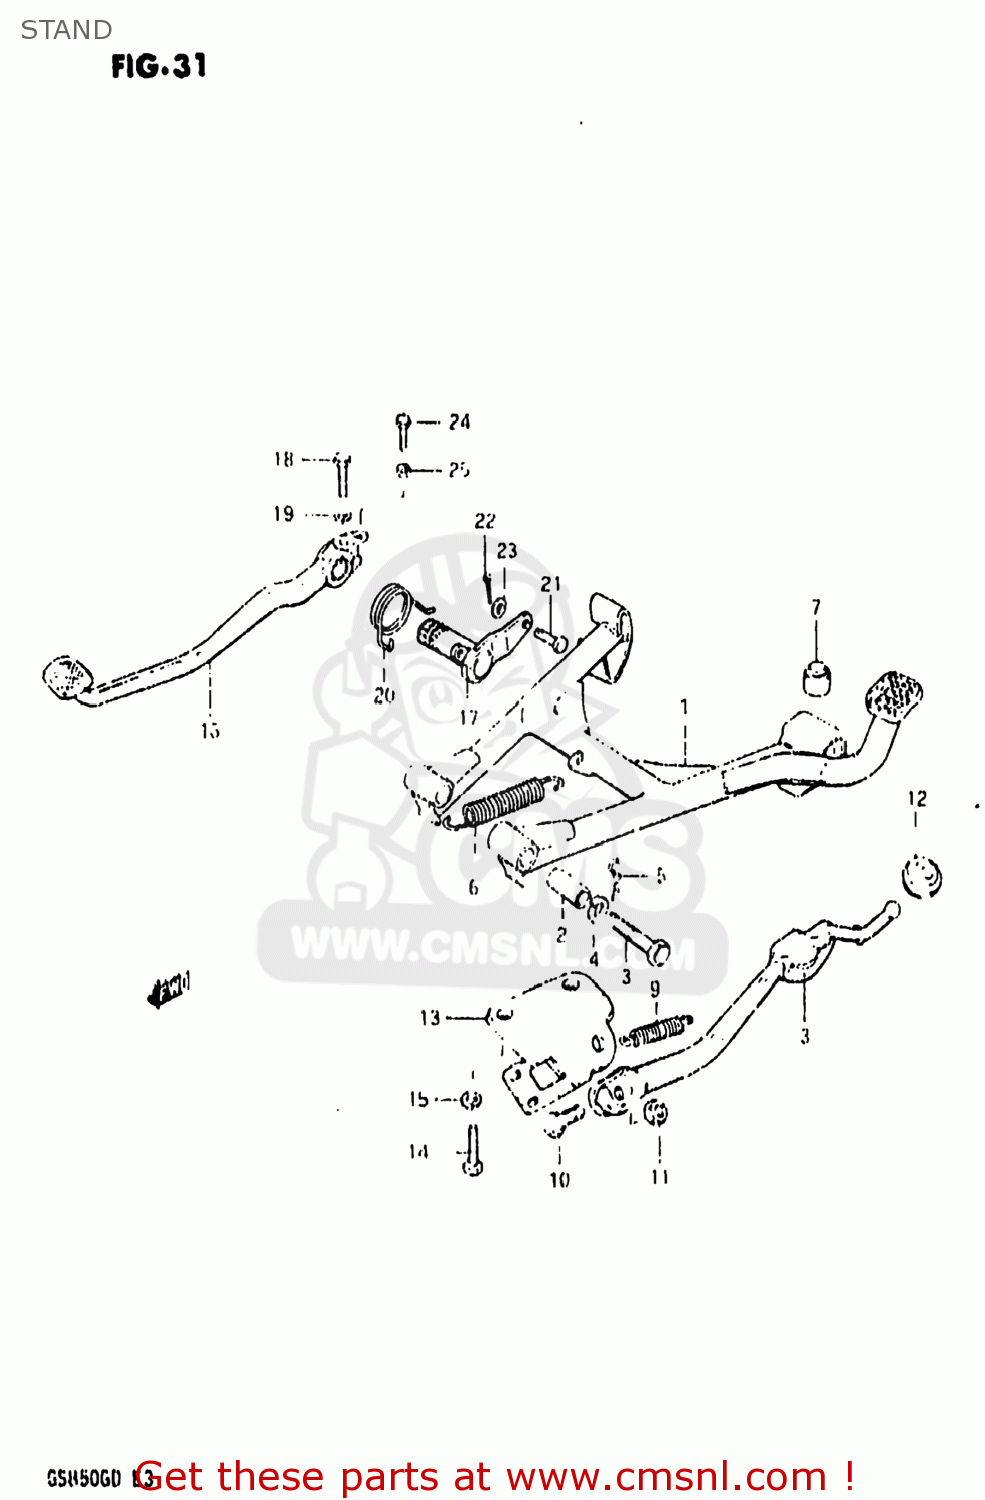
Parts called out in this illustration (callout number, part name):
1	STAND,CENTER
2	SPACER(10X16X38.8)
3	BOLT
4	LOCK WASHER
5	CLIP
6	SPRING
7	CUSHION
8	STAND,SIDE
9	SPRING
10	BOLT(10X30)
11	NUT
12	CUSHION
13	BRACKET,SIDE STAND
14	BOLT
15	LOCK WASHER
16	PEDAL,BRAKE
17	ARM,BRAKE PEDAL ROD
18	BOLT (8X30)
19	LOCK WASHER
20	SPRING
21	PIN
22	PIN
23	WASHER
24	BOLT
25	NUT
